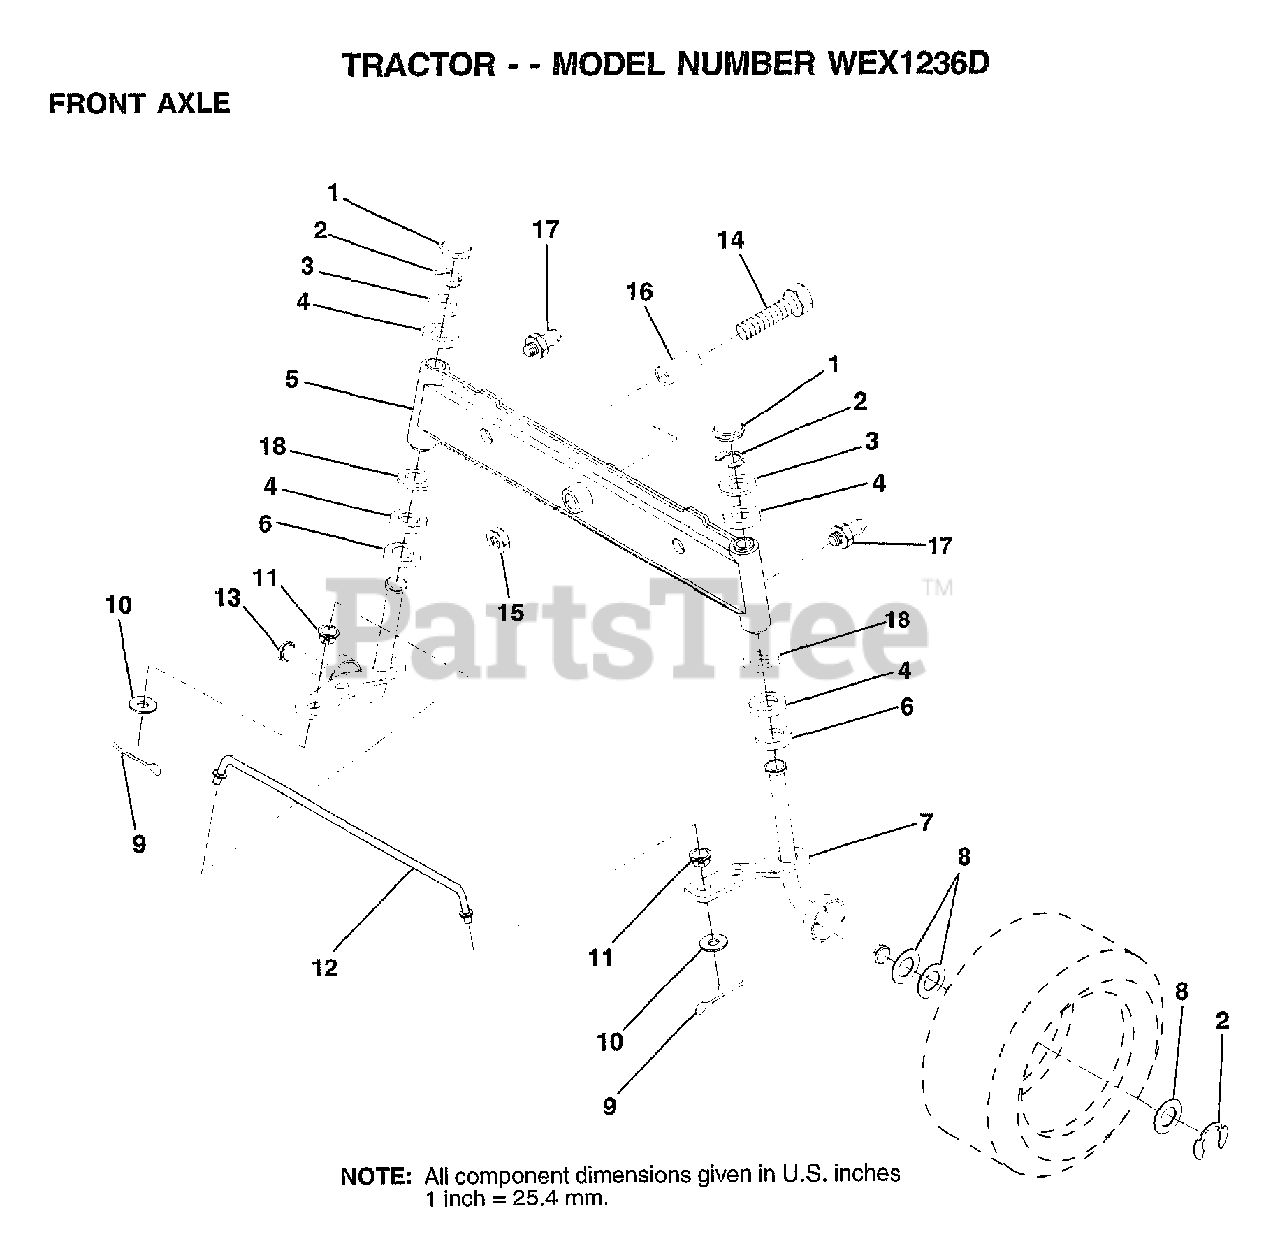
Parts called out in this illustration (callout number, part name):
1	CAP
2	RING
3	WASHER
4	COL. SRTG. BEAR.
5	AXLE ASM FRONT
6	WASHER .T
7	SPINDLE.ASSY.RH
8	WASHER
9	COTTER PIN
10	WASHER
11	BUSHING.DRAGLINK
12	TIE ROD
13	SPINDLE.ASSY.LH
14	BOLT HEX 5/8-11
15	"NUT-LOC,FLANGE LT"
16	BEARING
17	ZERK M
18	WASHER
